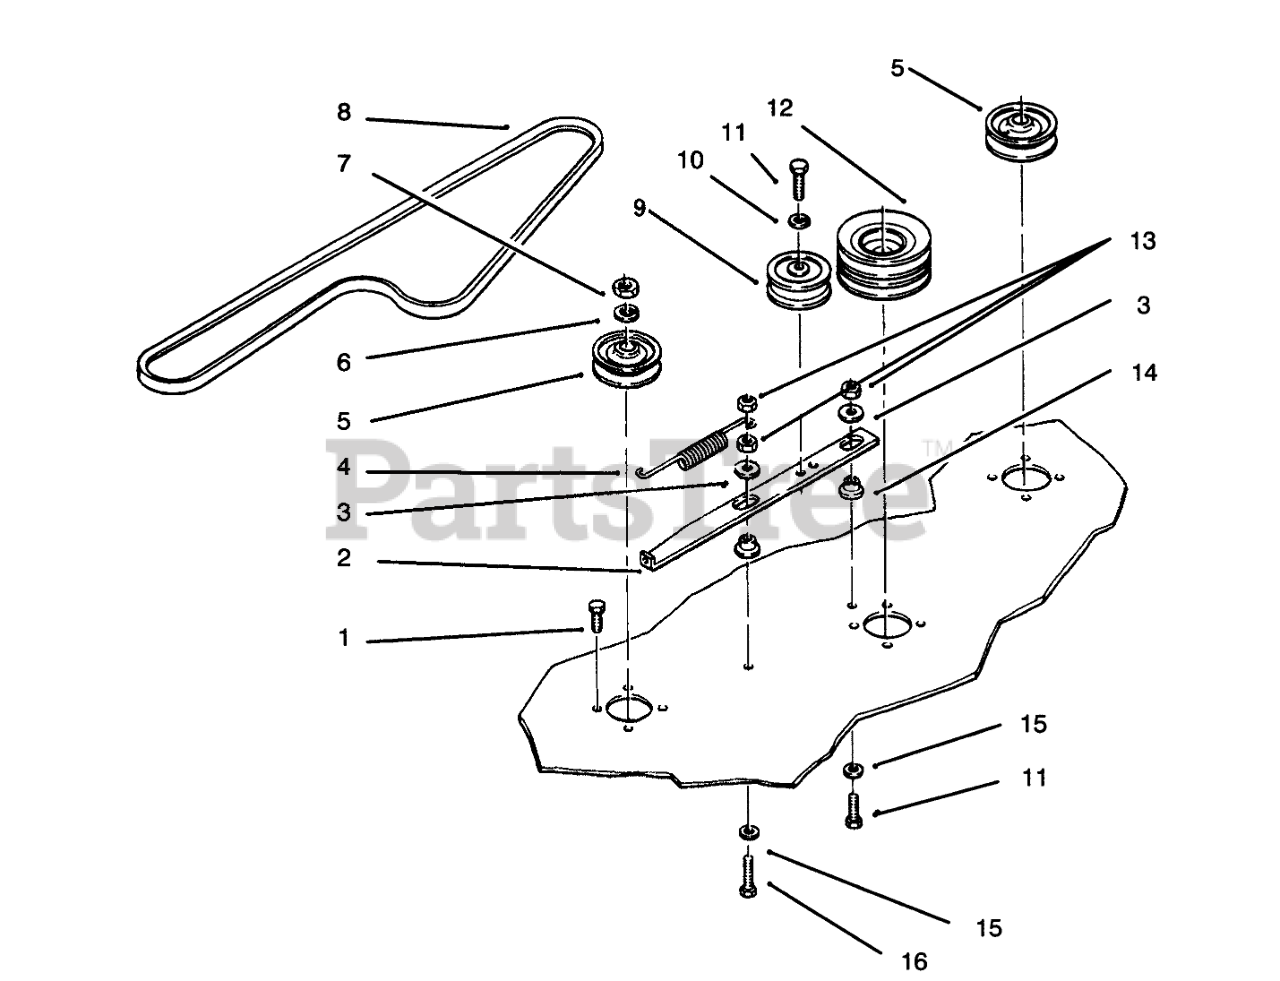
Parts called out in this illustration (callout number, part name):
1	SCREW-HH
2	BAR-IDLER SUPPORT
3	WASHER
4	SPRING-EXTENSION
5	PULLEY
6	WASHER-LOCK
7	NUT-JAM
8	V-BELT
9	PULLEY-IDLER
10	WASHER-LOCK
11	SCREW-HH
12	PULLEY CENTER
13	NUT-LOCK, NI
14	SPACER-BUSHING
15	WASHER
16	SCREW-HH
